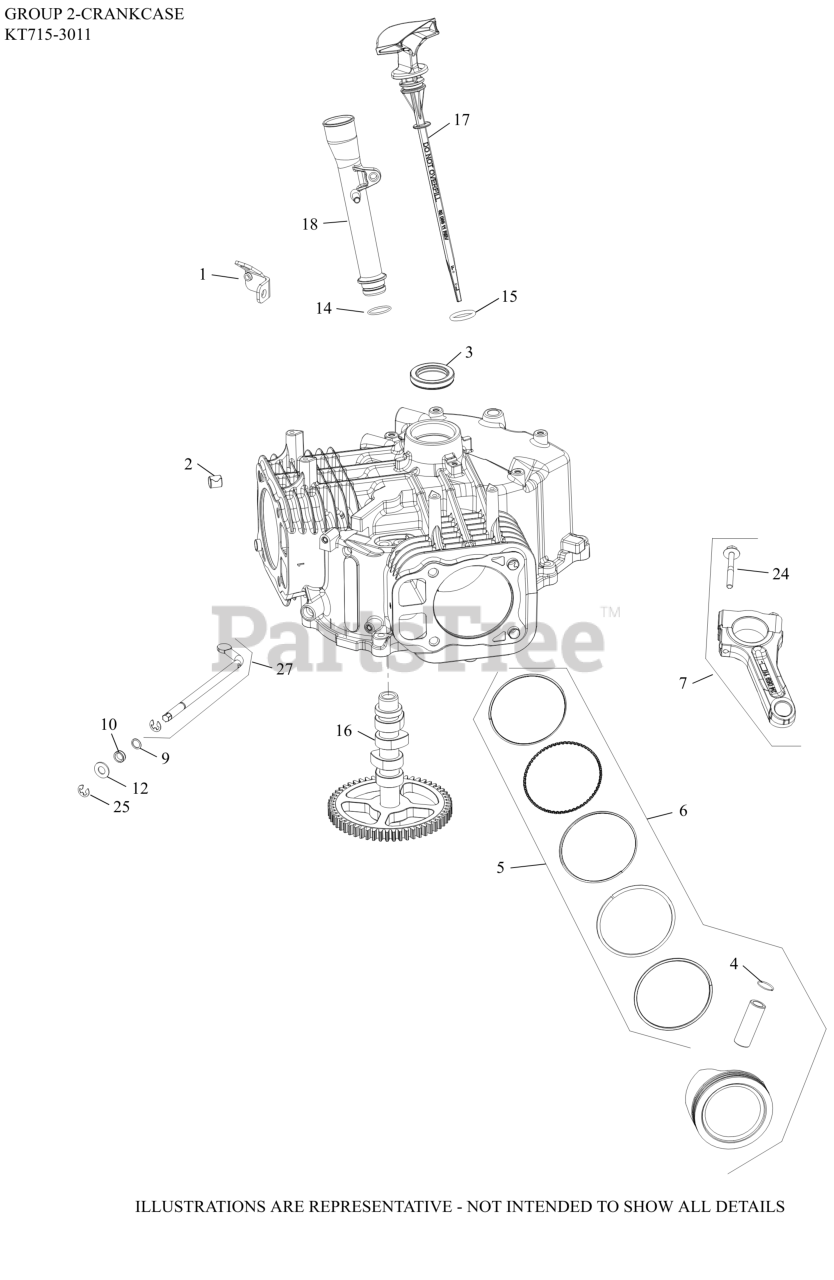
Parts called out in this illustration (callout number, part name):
1	BRACKET, OIL FILL TUBE
2	PIN, LOCATING
3	SEAL, OIL (HELIX LIP)
4	RETAINER, PISTON PIN
5	RING SET(STD)STYLE B-1.2mm Tp RING THICK
5	RING SET(.08)STYLE B-1.2mm RING THICK
5	RING SET(.25)STYLE B-1.2mm Tp RING THICK
5	RING SET(.50)STYLE B-1.2mm Tp RING THICK
6	KIT, PISTON 725CC (STD) STYLE B
6	KIT, PISTON 725CC (.08) STYLE B
6	KIT, PISTON 725CC (.25) STYLE B
6	KIT, PISTON 725CC (.50) STYLE B
7	ROD, ASSY CON (STD)-USE 24 067 30-S
7	ROD, ASSY CON(.25mm) -USE 24 067 31-S
9	WASHER, FLAT 11/32"
10	SEAL, GOVERNOR CROSS SHAFT
12	WASHER, FLAT 9 MM
16	CAMSHAFT ASSY
17	DIPSTICK, ASSY
18	TUBE ASSEMBLY, OIL FILL
24	KIT, ROD BOLTS-(#25086677S)
24	KIT, ROD BOLTS
25	CLIP, RETAINER GOVERNOR SHAFT
27	KIT, CROSS SHAFT
